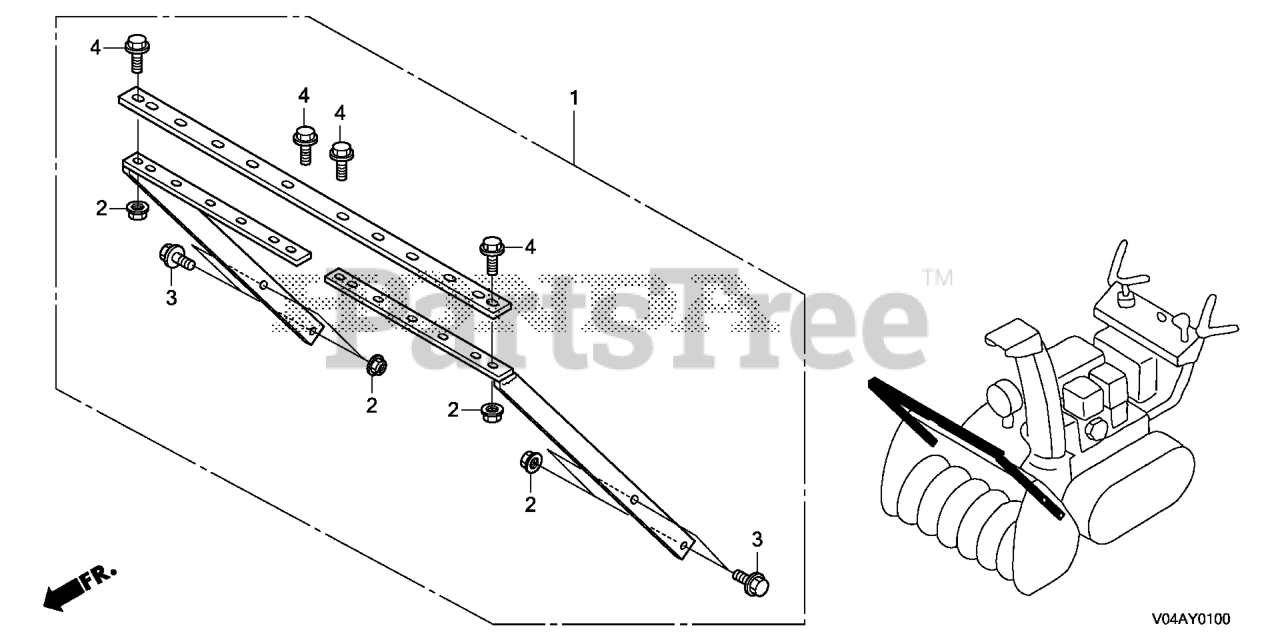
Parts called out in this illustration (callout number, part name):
1	BREAKER KIT, DRIFT (NA USE ALT:06768-V45-305AH)
2	NUT, SELF-LOCK (8MM)
3	BOLT, FLANGE (8X20)
4	BOLT, FLANGE (8X25)
